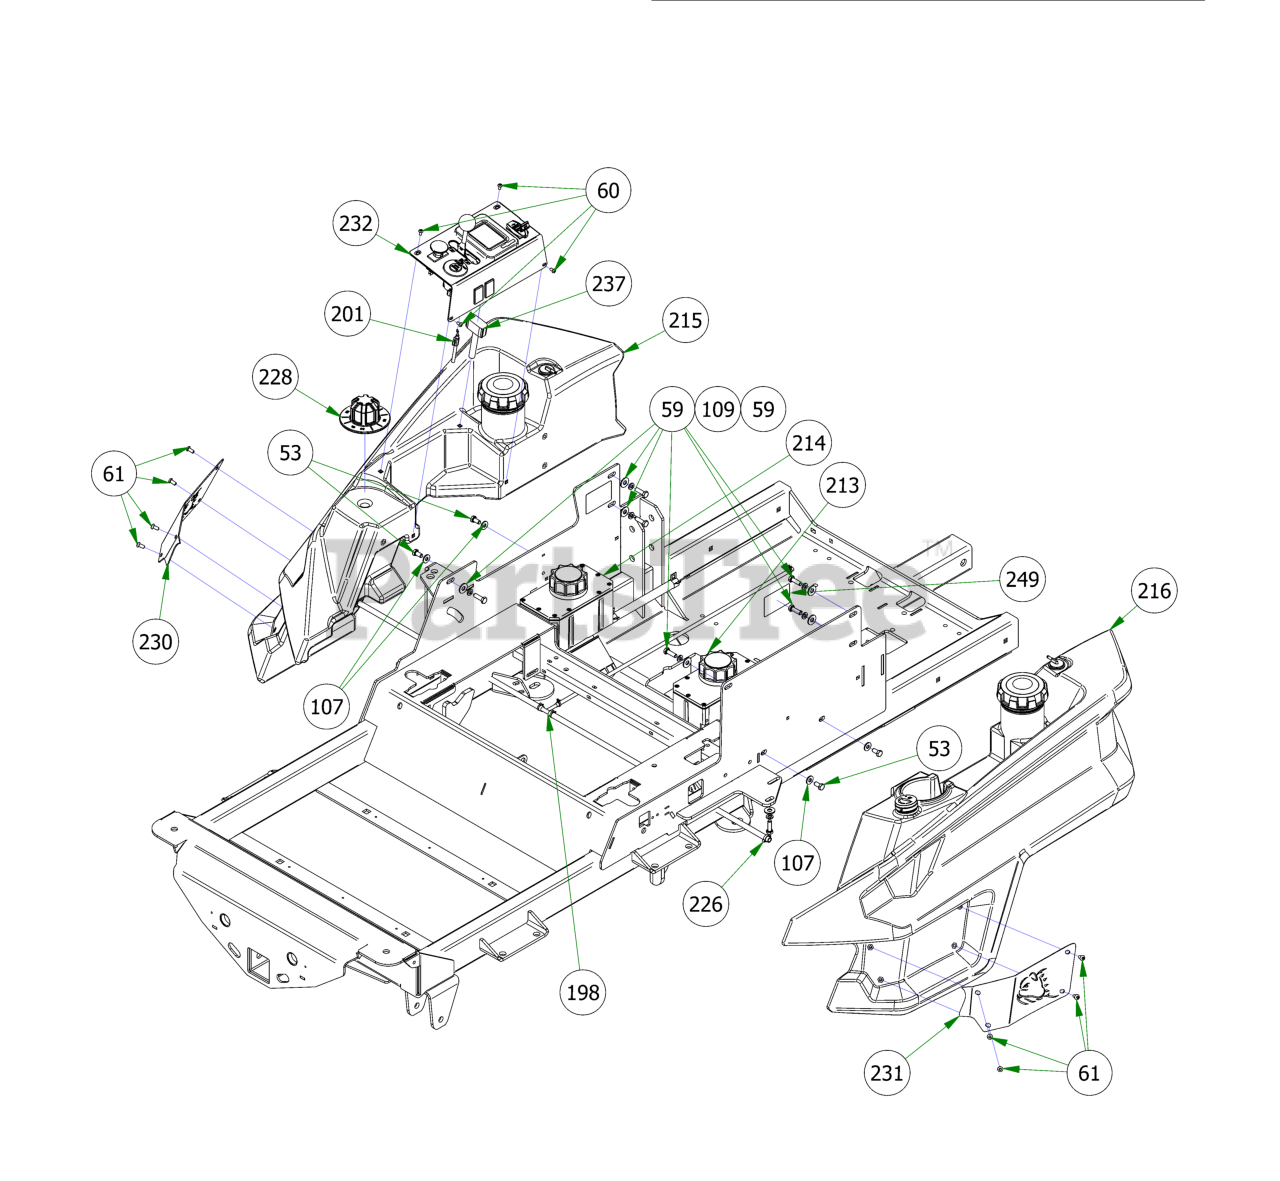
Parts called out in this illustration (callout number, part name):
5	.625 ID x 1.250 OD x .062 THK F/W Nylon
53	5/16-18 x 5/8 Hex Bolt
59	5/16-18 X 1 HEX CAP SCREW (GR.5) ZINC
60	10-32 X 3/8 BUTTON SOCKET CAP SCREW 18-8 STAINLESS STEEL
61	1/4-20 X 1/2 BUTTON SOCKET CAP SCREW 18-8 STAINLESS STEEL
107	1/4 USS FLAT WASHER (3/4 OD) ZINC
108	5/16 USS FLAT WASHER (7/8 OD) ZINC
109	5/16 SPLIT LOCKWASHER ZINC
119	5/8" Split Collar
198	2019 Rebel Rogue Renegade Fuel Line for Kohler
201	Outlaw Throttle Cable
213	LH Rogue Hydro Tank Assy
214	RH Rogue Hydro Tank Assy
215	2019 Right Rebel, Rogue, Renagade Fuel Tank (GAS)
216	2019 Left Rebel, Rogue, Renegade Fuel Tank (GAS)
224	2019 Renegade Gas Frame - Powdercoated
226	2 EAR CLAMP 12.5mm-15mm
228	2019 Deck Height Dial
230	2019 Outlaw Fuel Tank Insert - Right
231	2019 Outlaw Fuel Tank Insert - Left
232	Renegade Control Panel Assembly
237	2019 LCD Panel Harness-Renegade
249	Hydraulic Decal
